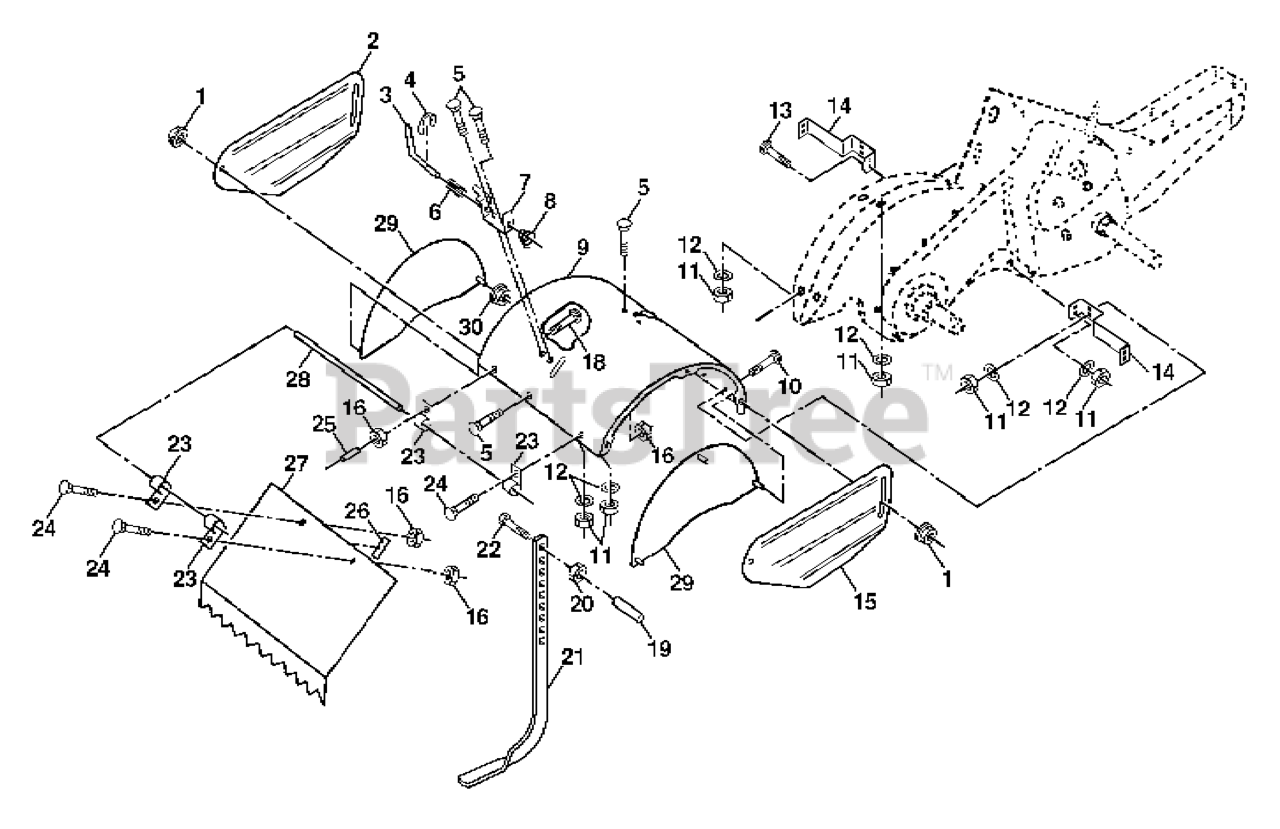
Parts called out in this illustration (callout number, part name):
1	NUT
2	SHIELD SIDE OUTER LH
3	STAKE PIN TI
4	KLIP RING TI
5	RP BOLT 5/16-18 X3/4 ZN/YEL GR
7	BRACKET.LATCH.STAKE.3.20.BLACK
8	SPRING CRT
9	SHIELD
10	BOLT
11	NUT
12	WASHER.LOCK.HVY.HLCL.SPR.5/16
13	BOLT.CARRIAGE.5/16-18
14	BRACKET.TINE.SHIELD.TILLER.BLA
15	SHIELD SIDE OUTER RH
16	Nut, Keps 1/4-20
20	NUT.HEX.3/8-16UNC
21	STAKE.DEPTH.16.CRT.BLACK
22	BOLT.375-16
24	BOLT
25	VINYL CAP TI
26	PAD IDLER TI
27	SHIELD LEVELING
28	PIN.HINGE.TILLER
29	SIDE SHIELD
30	LOCKNUT-FLANGE 5/16-18
